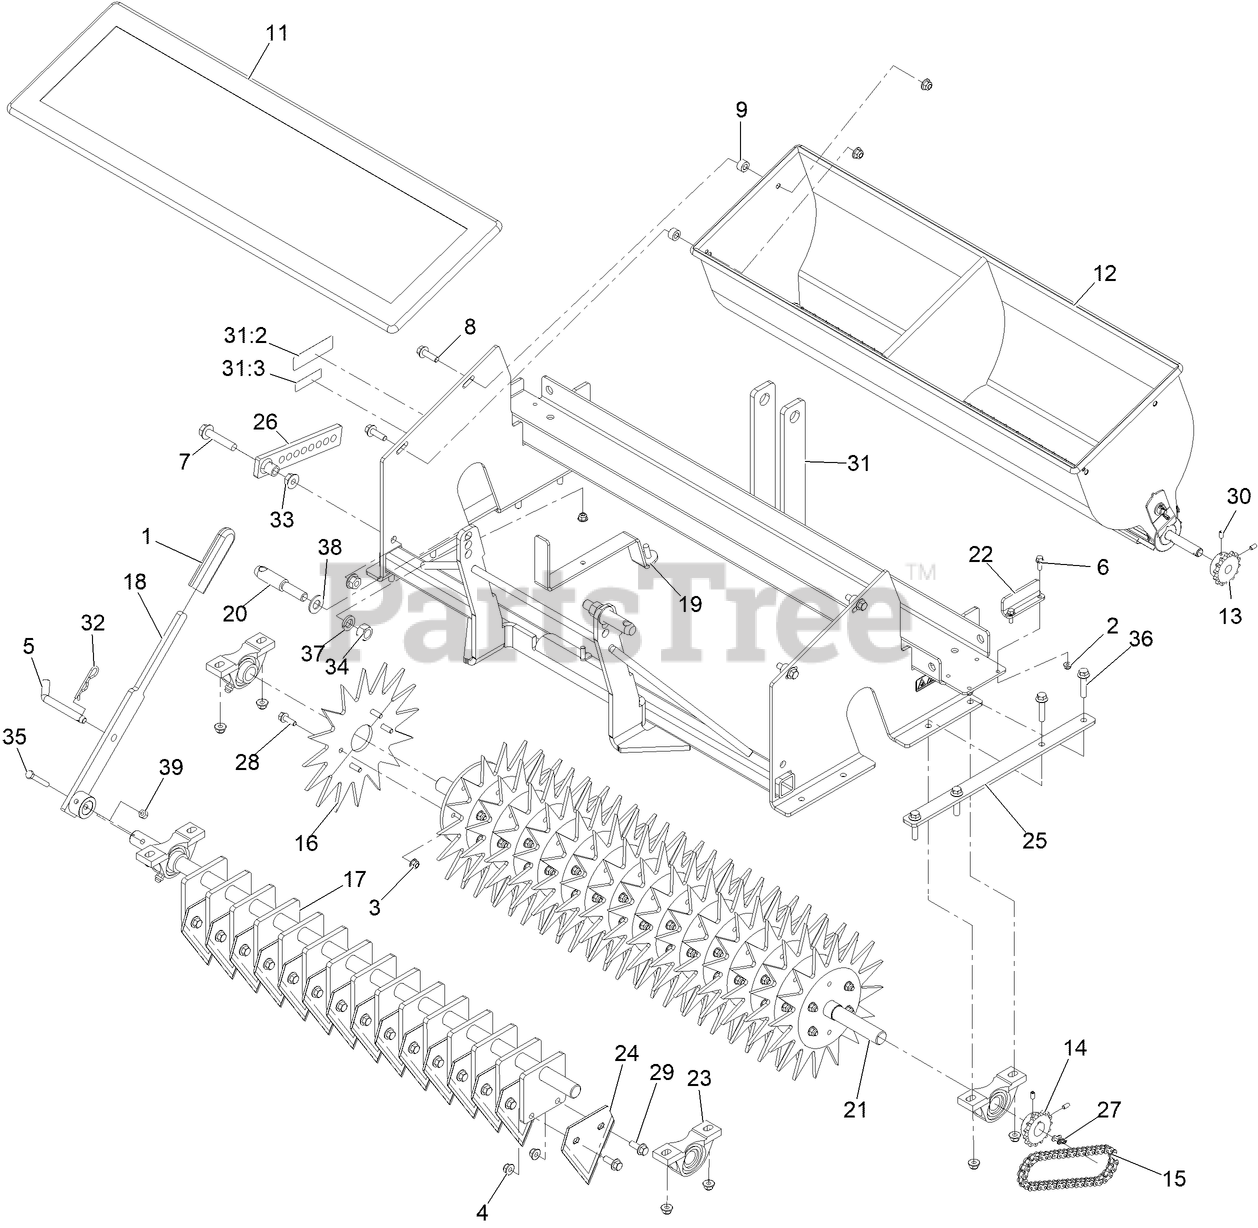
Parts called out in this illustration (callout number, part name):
1	GRIP-LEVER
3	NUT-HF, NI
4	NUT-HF, NI
5	1/2 X 4-3/4 BENT PIN
6	Screw-HHF
7	SCREW-HHF
8	SCREW-HHF
9	BUSHING-HOPPER
11	SLIT SEEDER DROP COVER
12	36" SLIT SEEDER HOPPER
13	SPROCKET-UPPER,SEEDER\NDA
14	SPROCKET-LOWER,SEEDER\NDA
15	Chain-Roller
16	Star, Slit Seeder
17	Shaft-Sq Plate [blk-Txt]
18	Handle-Slit Seeder [blk-Txt]
19	Handle-Gate [blk-Txt]
20	PIN-LIFT
21	DISC-SLIT SEEDER
22	Bracket-Weight [blk-Txt]
23	PILLOW BLOCK BEARING
24	4' SLICING KNIFE\NR201313
25	PLATE-DOUBLER
26	Arm-Ctrl, Seeder [blk-Txt]
27	Link-Chain
28	SCREW-HHF
29	SCREW-HHF 3/8-16 X 1
30	Screw-Set, HSH
31	Split Seeder Frame ASM W/Decals
31:2	DECAL-WARNING, TINES
31:3	DECAL-WARNING
32	PIN-HAIR
33	NUT-HHF
34	NUT-HEX
35	SCREW-HH
36	SCREW-HHF
37	WASHER-LOCK
38	WASHER-FLAT
39	NUT-LOCK, NI
